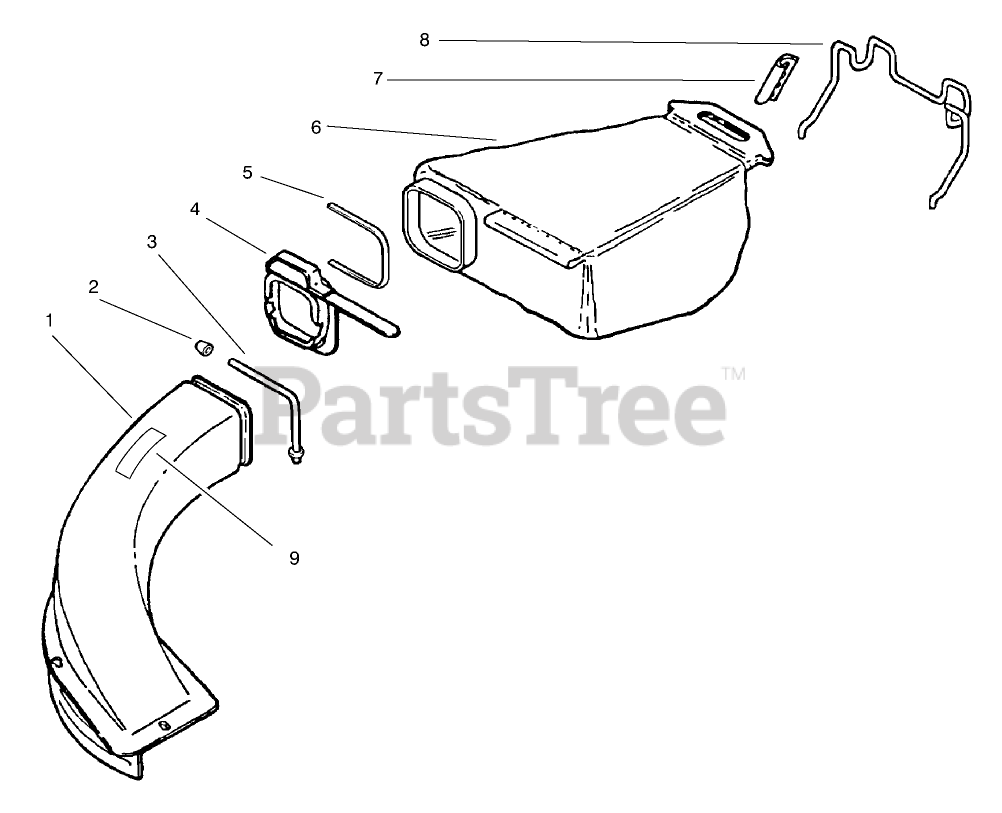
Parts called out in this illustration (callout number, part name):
1	Chute & Support Assembly (Incl. Ref. #2, 3, & 9)
2	NUT-CAP
3	SUPPORT-CHUTE
4	ASM-Adapter
5	STRAP-TIE
6	BAG - GRASS
7	Bracket
8	HANGER-WIRE
9	DECAL - DANGER
